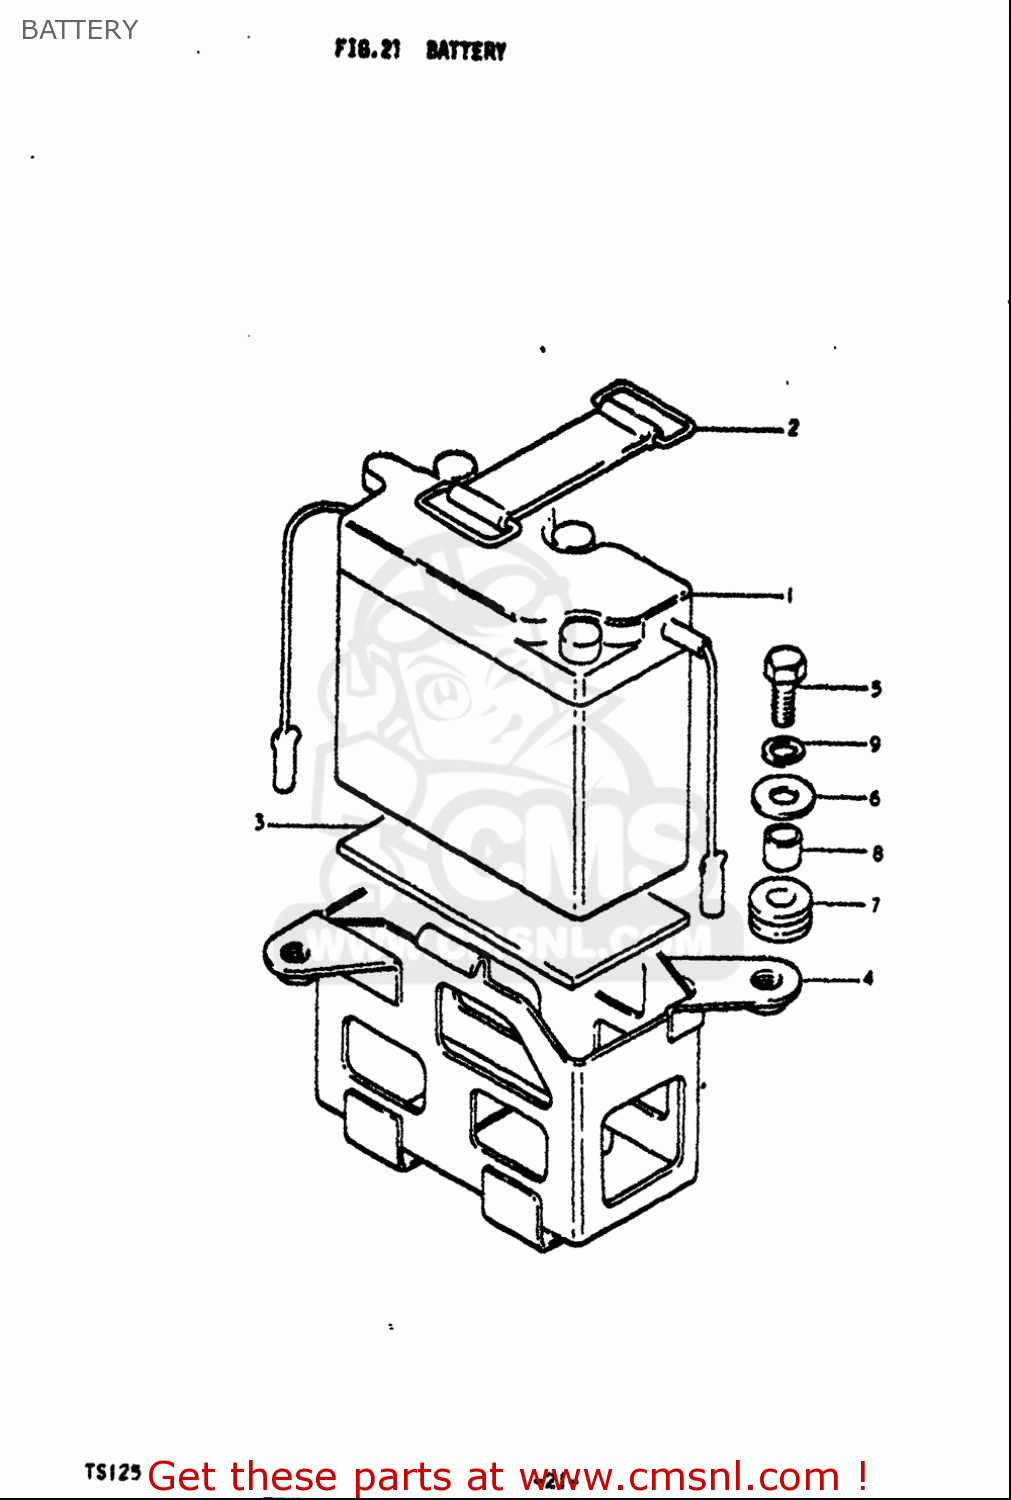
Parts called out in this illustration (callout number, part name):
1	BATTERY(6N4B-2A,6V4.2AH)
2	BAND
5	BOLT
6	WASHER(6.5X20X1.2)
8	SPACER,6.5X9X7
9	WASHER,LOCK
